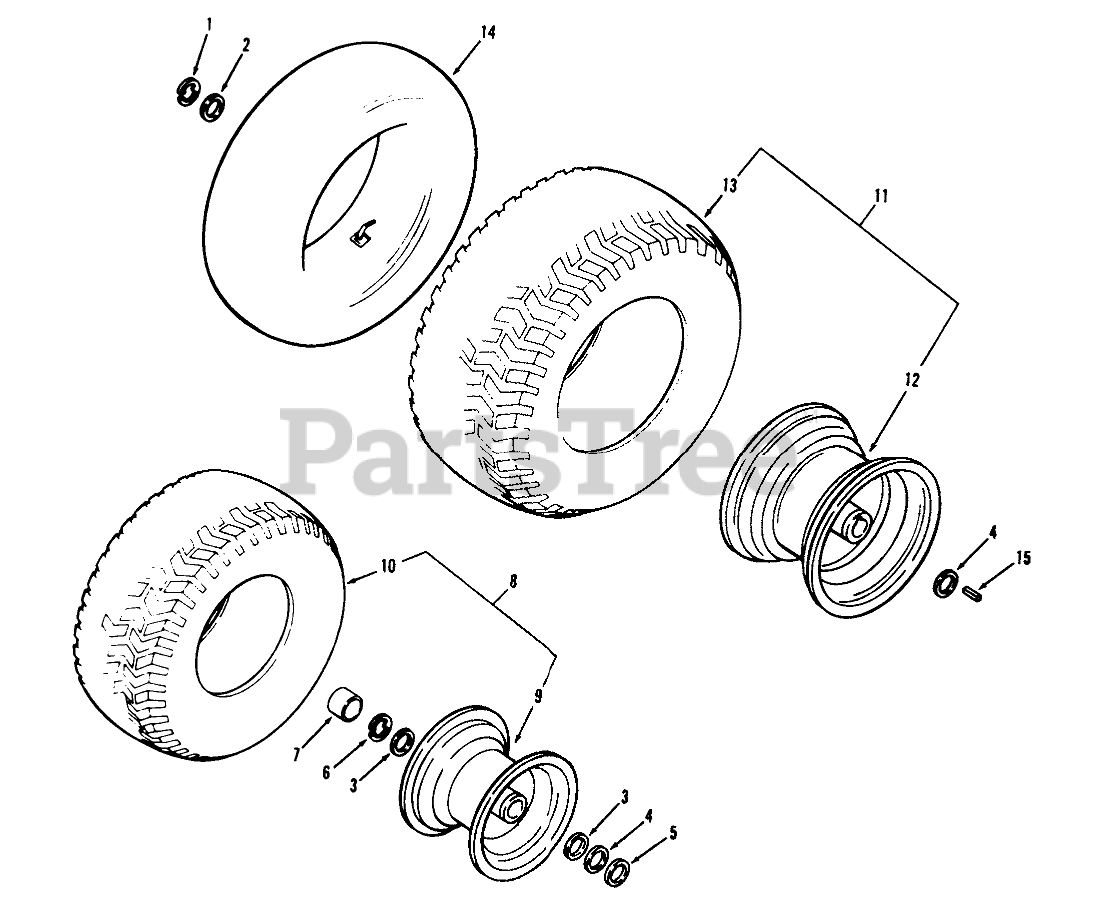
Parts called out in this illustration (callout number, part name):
1	E Ring
3	WASHER-SHIM
4	WASHER
5	Washer
6	Snap Ring
7	HUB CAP
8	Assy-Wheel & Tire Front
8	Front Wheel
9	Front Wheel
10	TIRE
11	Assy-Wheel & Tire Rear
12	Rear Wheel
13	TIRE 18 X 8.50 X 8
14	Tube-Inner
15	SQ KEY
